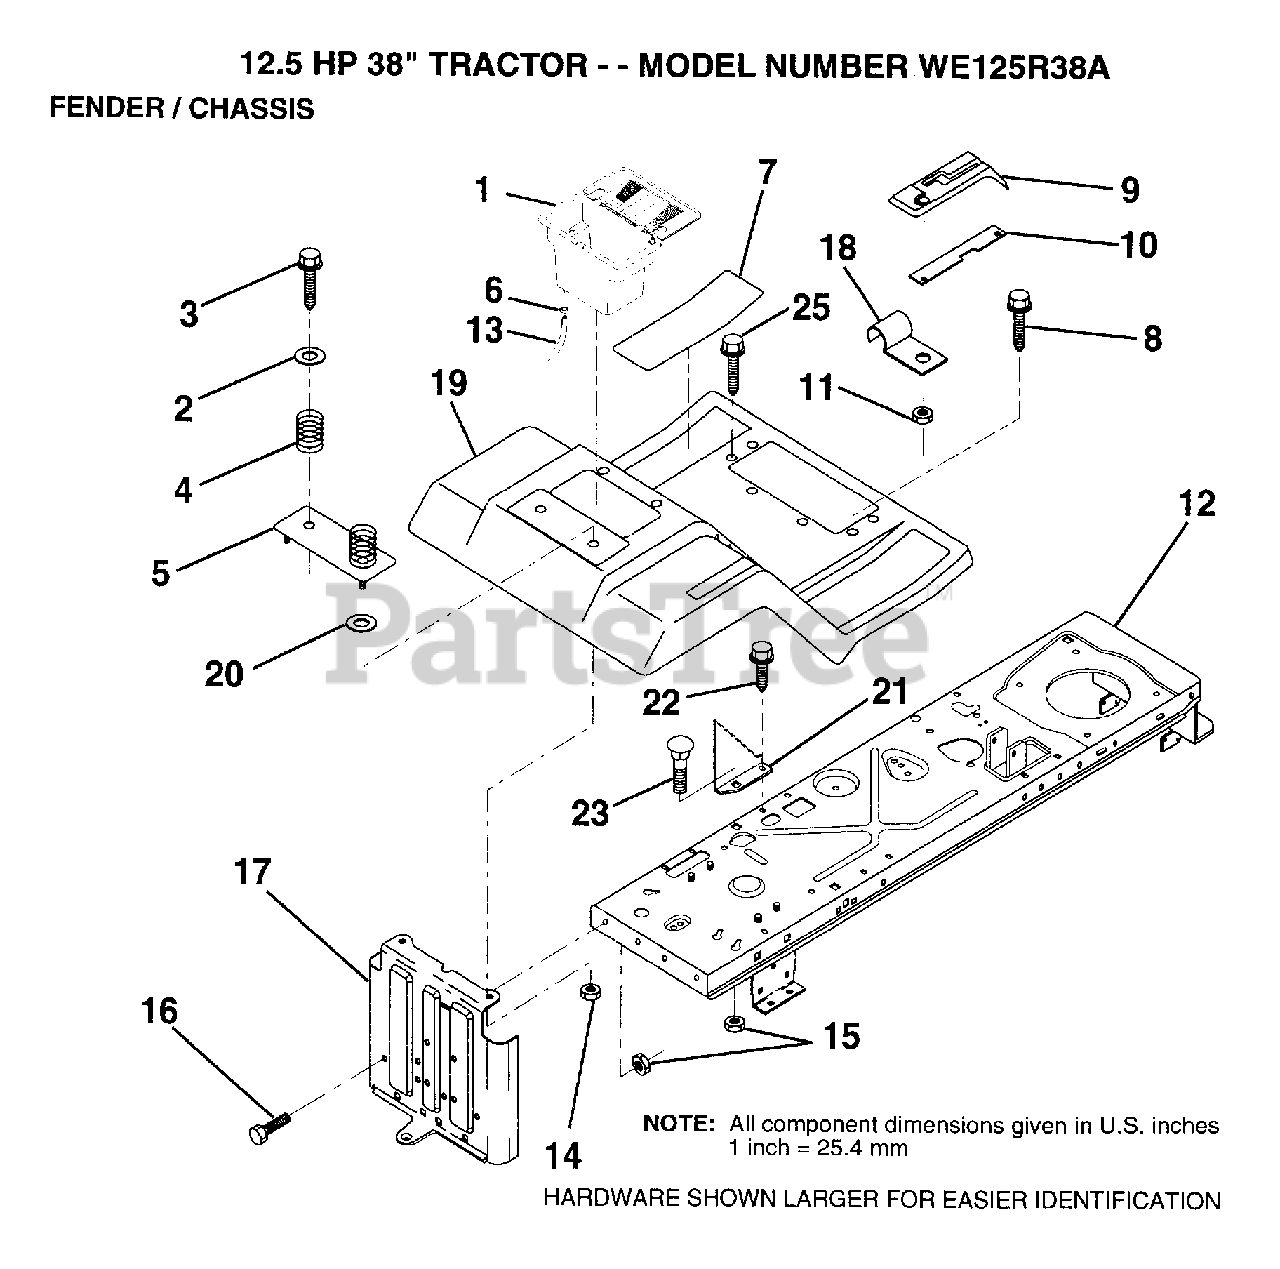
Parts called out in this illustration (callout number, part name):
2	WASHER
3	SCREW
4	SPRING COMPRESSIO
5	"PLATE, BATTERY"
6	HOSE CLAMP T
7	PAD FOOTREST
8	SCREW
10	"SHIFT LOCK, BAR"
11	NUT
13	TUBE T
14	NUT
16	BOLT
17	DRAWBAR
18	"CLIP,INSULATOR"
22	SCREW LT
25	SCREW TI
